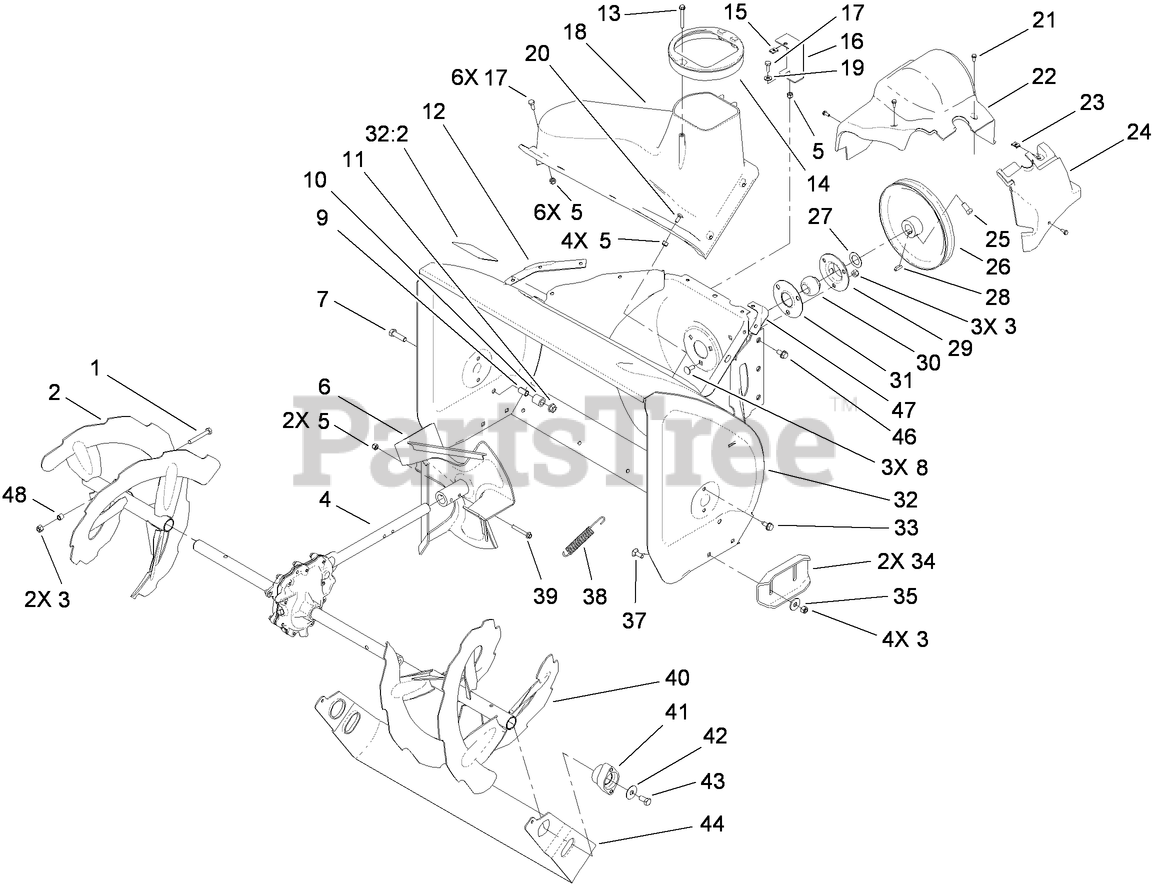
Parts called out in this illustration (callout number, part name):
1	SCREW-HH
2	RH AUGER ASM
3	NUT-LOCK, NI
5	NUT-LOCK, NI
6	IMPELLER ASM
7	SCREW-HH
8	SCREW-CARR
9	SPACER-SCRAPER, STOP
10	CUSHION-SCRAPER, STOP
11	NUT-HF
12	SEAL-FLANGE, COVER
13	SCREW-PLASTITE
14	GUIDE-CHUTE
15	NUT-SPEED
16	BRACKET-COVER, CLIP NUT
17	SCREW-HH
19	WASHER-FLAT
20	BOLT-CARR
21	SCREW-HWH
23	NUT-SPEED
24	COVER-EXTENSION, BELT
25	SCREW-SET, SQH
27	WASHER-THRUST
28	KEY-WOODRUFF
29	FLANGE-CUP, BEARING
30	BEARING-BALL
31	FLANGE-CUP, BEARING
32	HOUSING-AUGER, 28 INCH
32:2	DECAL-DANGER
33	SCREW-HWHTF
35	WASHER
37	SCREW-CARR
38	SPRING-SCRAPER
39	SCREW-HHF
40	LH AUGER ASM
41	BEARING-AUGER
42	WASHER
43	SCREW-HH
44	SCRAPER-PIVOTING, 28 INCH
46	SCREW-HWHTF
48	SPACER
